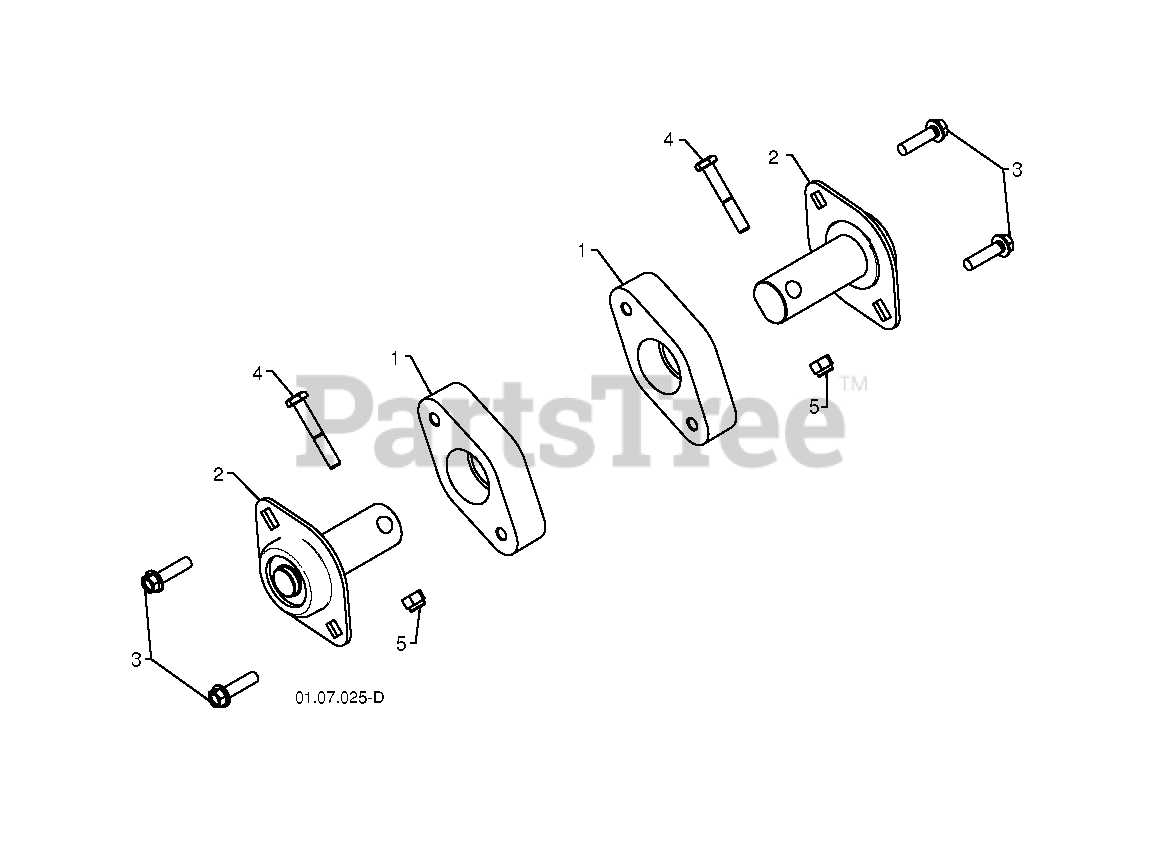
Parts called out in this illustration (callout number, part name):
1	BEARING RETAINER, PLASTIC
2	BEARING.BALL.AUGER.FLAT.FLAT
3	SCREW, HEX HD 5/16X1
4	SCREW.HEX.HD1/4-20X
5	LOCKNUT
